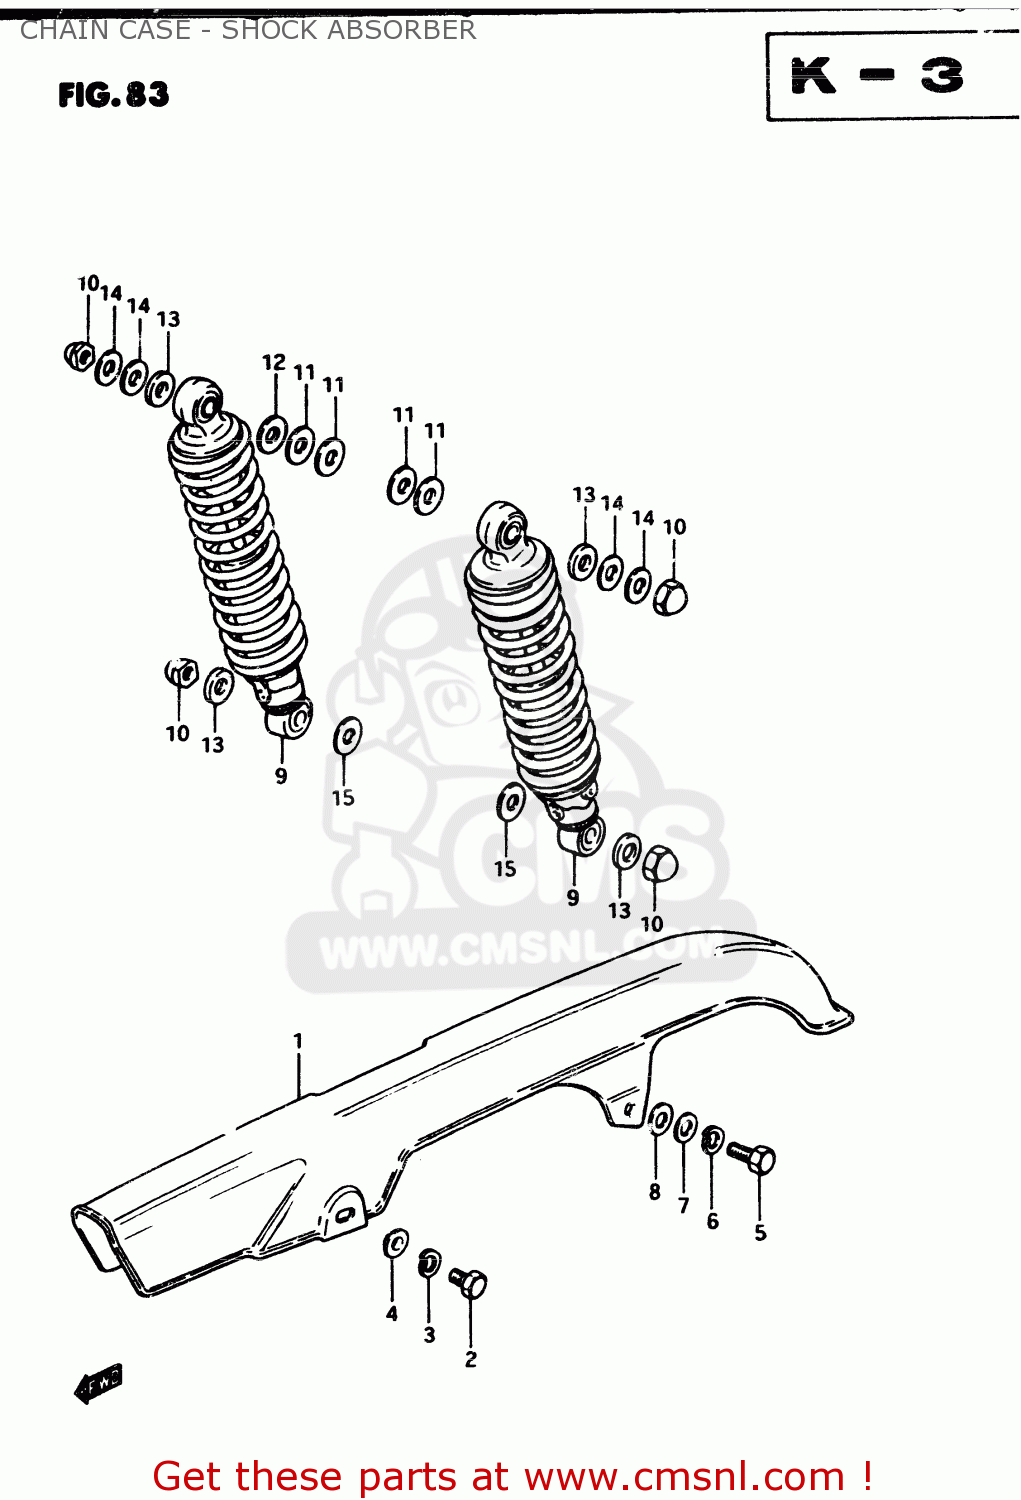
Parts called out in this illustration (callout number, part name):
1	CASE,CHAIN
2	BOLT
3	LOCK WASHER
4	WASHER,LOCK
5	BOLT
6	LOCK WASHER
7	WASHER
8	WASHER(6.5X18X1)
9	SHOCK ABSORBER, REAR
10	NUT, LOWER LH
11	WASHER
12	WASHER (12.5X24X3.2)
13	WASHER
14	WASHER(10.5X24X3.2)
15	WASHER (12.5X24X1.6)
